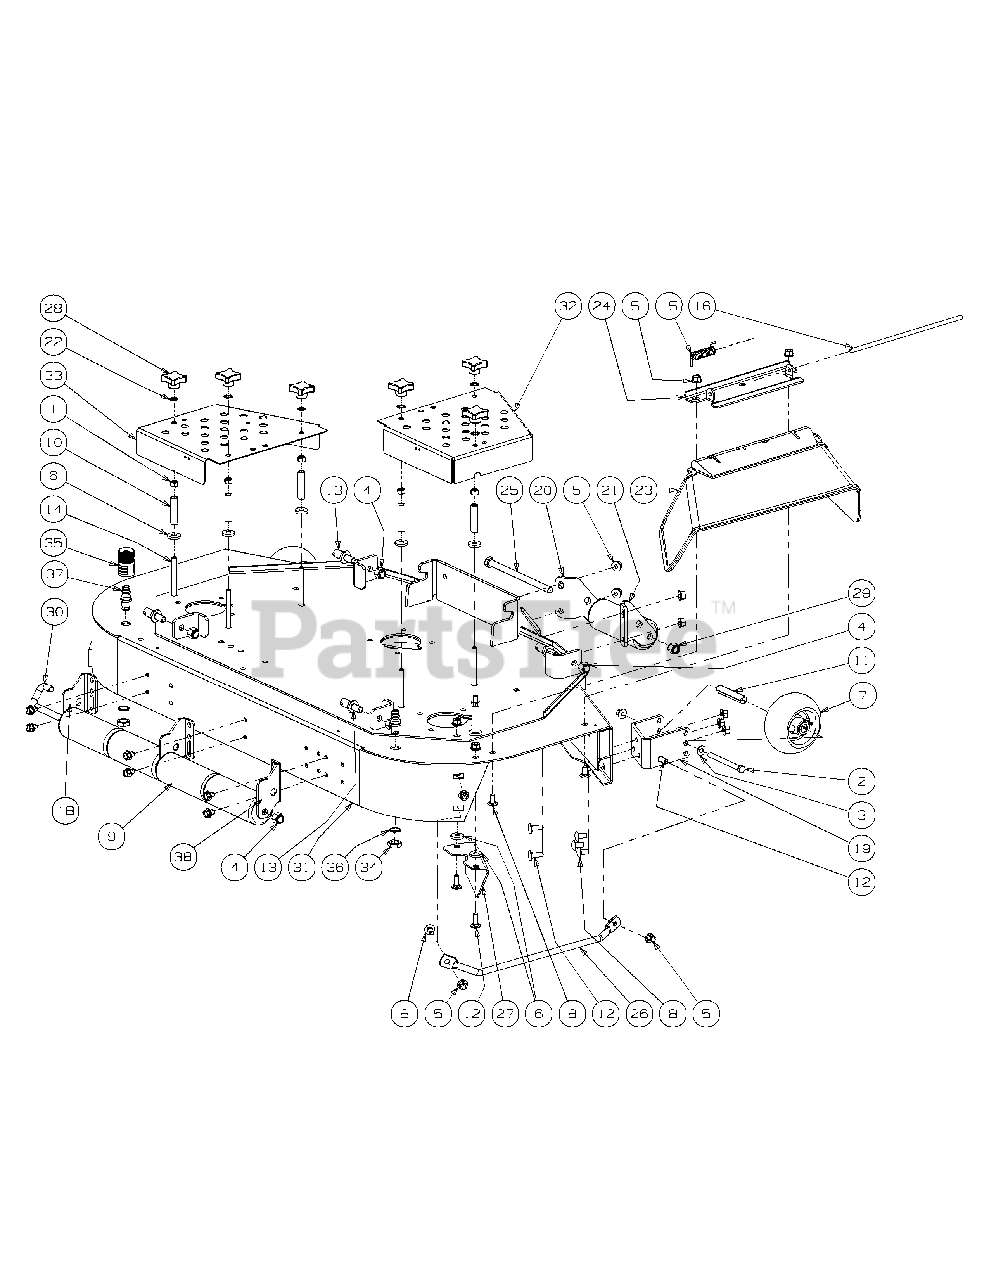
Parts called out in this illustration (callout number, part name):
1	Hex Nut 3/8-16
2	Hex Cap Screw, 3/8-16, 3.75
3	Flat Washer, 3/8
4	Lock Nut, Nylon Insert, 1/2-13
5	Flange Lock Hex Nut, 3/8-16
6	Idler Washer
7	Complete Wheel, 5.00 Dia.
8	Carriage Bolt, 3/8-16 x .75 Lg.
9	Front Roller
10	Spacer Stop Deck
11	Wheel Spacer
12	Carriage Bolt, 3/8-16 x 1
13	Pin, 5/8 Dia. x 1.2 Lg.
14	Carriage Bolt, 3/8-16 x 3.5 Lg
15	Torsion Spring, 0.4ID x 2.16Lg
16	Chute Deflector Rod
17	Hex Index Washer Screw, 3/8-16, .05
22	External Washer, 3/8
23	Deflector Chute
24	Deflector Chute Bracket
25	Hex Cap Screw, 1/2-20 x 7.50
26	Finger Guard
28	Plastic Knob
29	Lock Nut, Nylon Insert, 1/2-20
30	J-Hook w/ Threaded Roller
31	48 Fabricated Deck Assembly
32	Belt Cover, RH
33	Belt Cover, LH
34	Hex Nut, M16-1.5
35	Water Nozzle Adaptor
36	Lock Washer, 17 x 23.8 x 1.95
37	Deck Water Nozzle
